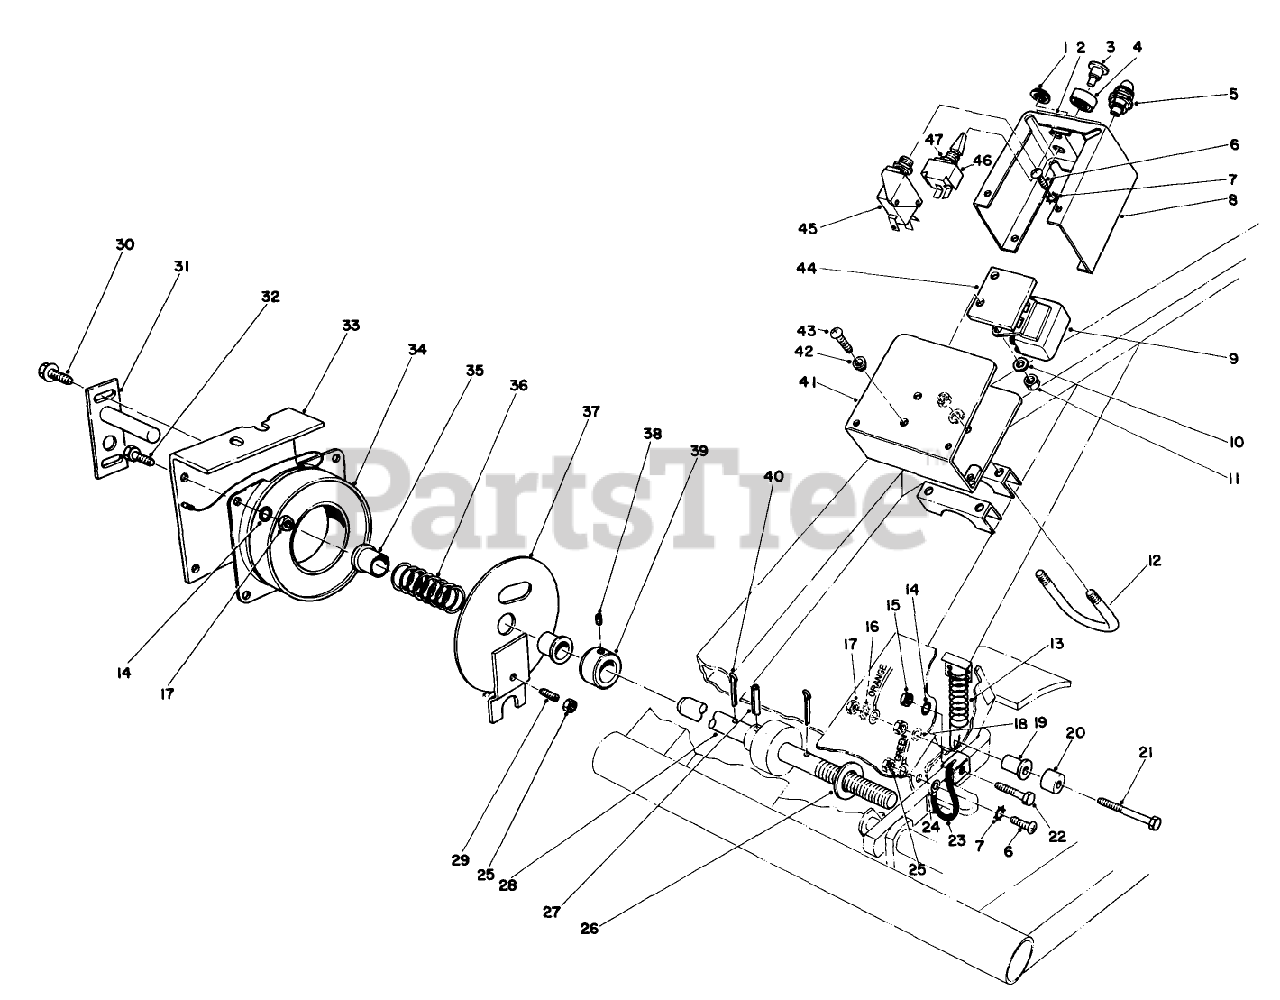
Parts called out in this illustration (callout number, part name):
1	NUT-BULB
2	SPEED CONTROL DECAL
3	BUTTON-PUSH
4	BEZEL
5	Light-Warning
6	SCREW-PPH
7	WASHER-LOCK/EXT
8	Cover-Box
9	Switch-Relay
10	WASHER-FLAT
11	NUT-LOCK, NI
12	MUFFLER CLAMP
13	Extension Spring Assembly
14	WASHER-LOCK
15	NUT-JAM
16	WASHER-LOCK/EXT
17	NUT-HEX
18	WASHER-FLAT
19	NUT-INSERT
20	CONTACT SPACER
21	SCREW-HH
22	SCREW-HH
23	Grounding Clip Assy (w/wire)
24	PIN-COTTER
25	NUT-HEX
26	SPACER
27	PIN-SPRING
28	TRACTION PEDAL SHAFT
29	SCREW-HSH
30	SCREW-HHF
31	Shaft
32	SCREW-HH
33	BRACKET R
34	CORE-FIELD, COIL
35	BUSHING-FLANGE
36	SPRING-COMPRESSION
37	Clutch Plate
38	SCREW-HSH
39	Collar (Incl. Ref.#38)
40	PIN-COTTER
41	Housing
42	INSULATOR SCREW
43	10-24 X 5/8 PAN HD MS
44	Pad-Relay Mounting
45	Switch
46	Switch-Light (Incl.Ref.#1 & 47)
47	NUT-LOCK
